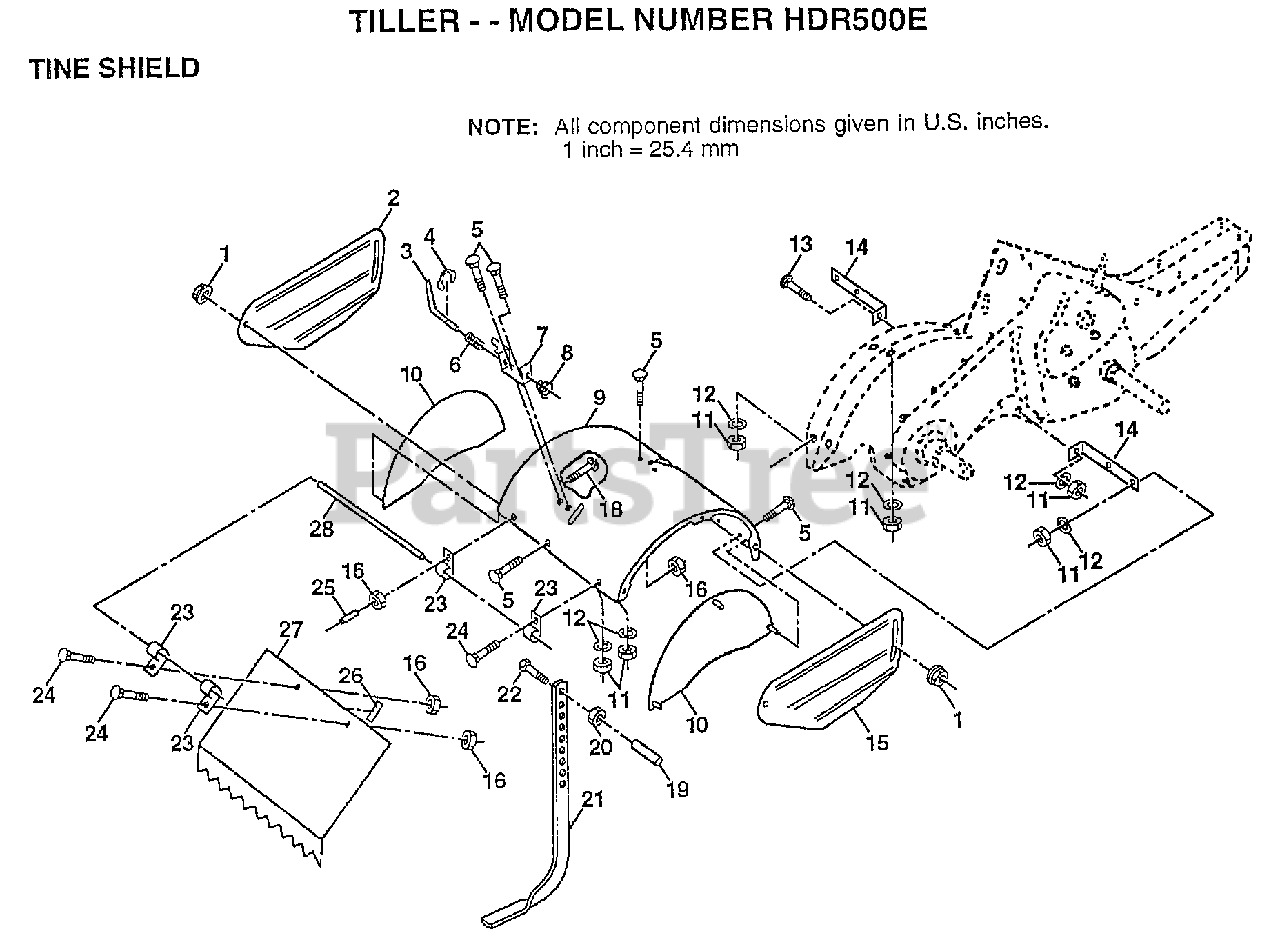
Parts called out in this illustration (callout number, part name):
1	NUT
2	SHIELD.SD.OUT.LH
3	STAKE PIN TI
4	KLIP RING TI
5	BOLT
6	SPRING TI
7	LATCH BRACKET TI
8	SPRING CRT
9	SHIELD TINE
10	SHIELD.SD.INNER
11	NUT.HEX.5/16-18
12	LOCKWASHER
13	BOLT
14	BRKT SHIELD TINE
15	"SHIELD TINE,SIDE"
16	NUT
18	BOLT
19	GRIP CRT
20	NUT.HEX.3/8-16UNC
22	BOLT
23	HINGE CRT
24	BOLT
25	VINYL CAP TI
26	PAD IDLER TI
27	"SHIELD,LEVEL"
28	PIN HINGE
